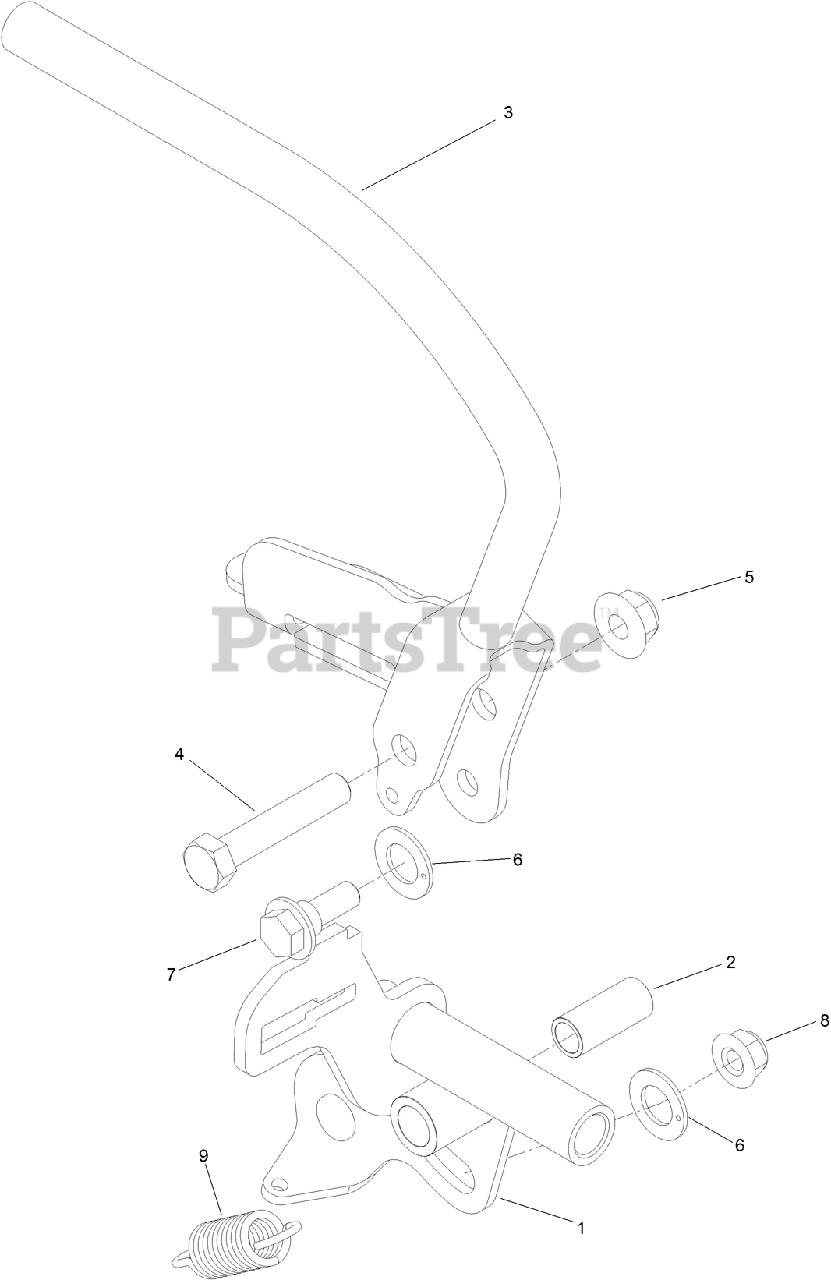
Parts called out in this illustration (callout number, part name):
2	BEARING-SLEEVE
3	LEVER-LH
4	SCREW-HH
5	NUT-HF, NI
6	WASHER-THRUST
7	SCREW-SHOULDER
8	NUT-HF, NI
9	SPRING-EXTENSION
